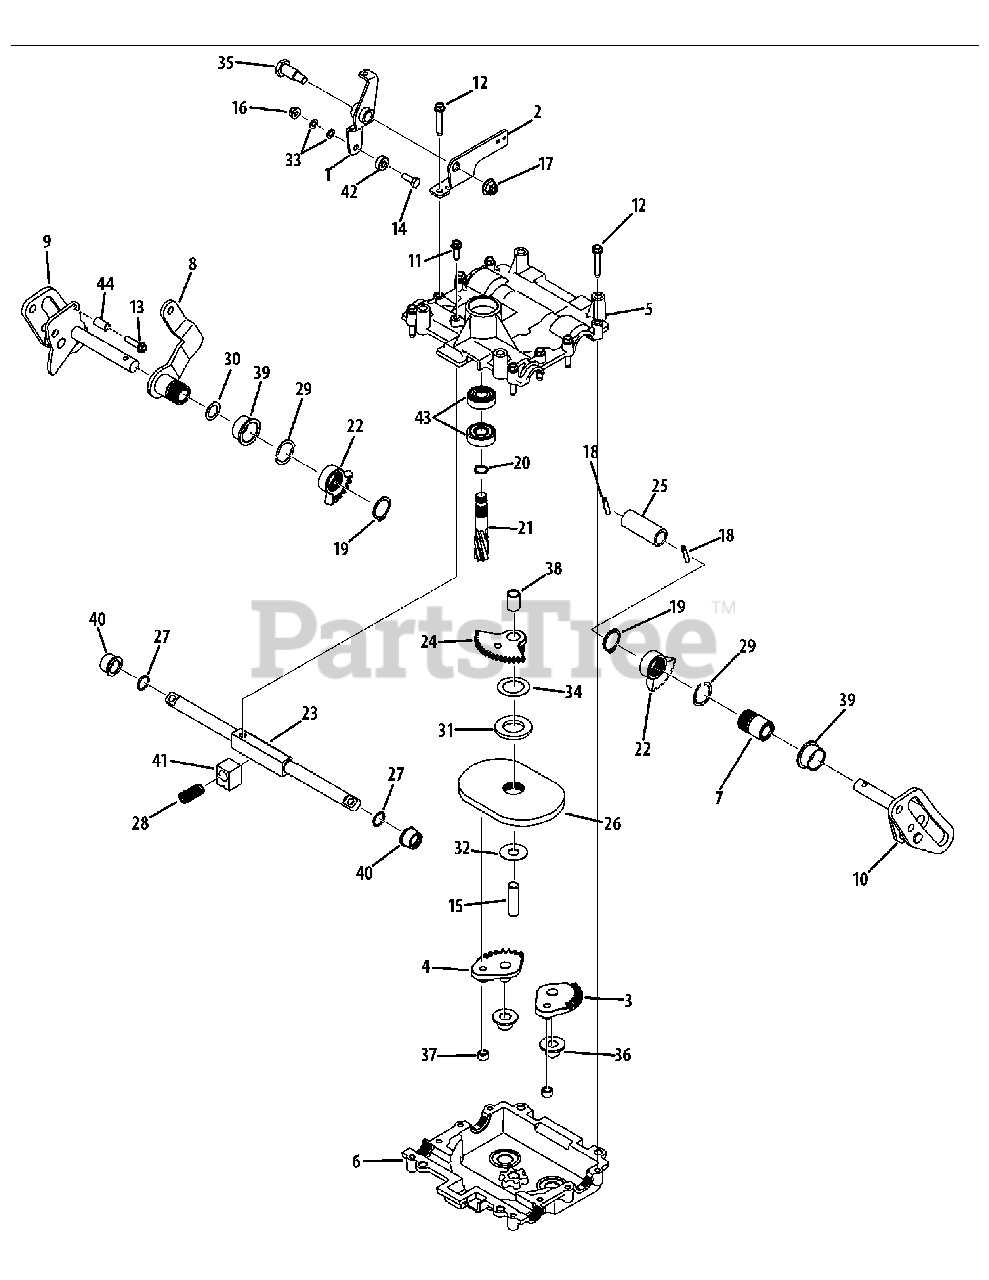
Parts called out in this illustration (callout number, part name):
1	Cam Plate Assembly
2	Neutral Bracket
3	LH Steering Gear Assembly
4	RH Steering Gear Assembly
5	Upper Steering Housing
6	Lower Steering Housing
7	Vertical Hydro LH Arm Assembly
8	Vertical Hydro RH Arm Assembly
9	RH Cam Assembly
10	LH Cam Assembly
11	Hex Washer Screw, 1/4-20 x 0.750
12	Hex Washer Screw, 1/4-20 x 1.500
13	Hex Washer Screw. 1/4-20 x 1.000
14	Hex Screw, 1/4-20 x .75
15	Steering Shaft
16	Hex Lock Nut, 1/4-20
17	Flange Lock Nut, 3/8-16
18	Spirol Pin, 3/16 x 1.00
19	Snap Ring, 1.0
20	Retaining Ring, .56
21	Pinion Gear, 7-Tooth
22	Steering Gear, 26-Tooth
23	Synchro Rack Gear
24	Steering Gear, 53-Tooth
25	Speed Cam Tube
26	Hydro Steering Cam
27	O-Ring, .625 x .07
28	Compression Spring, .531 x 1.25
29	Wave Spring, 24.22 x 32 x 1.98
30	Flat Washer, .635 x .930 x .033
31	Flat Washer, 1.01 x 1.75 x .172
32	Flat Washer, .508 x 1.325 x .040
33	Flat Washer, .260 x .455 x .048
34	Thrust Washer, 1.007 x 1.542 x .03
35	Shoulder Screw, 3/8-16 x .500 x .835
36	Flange Bearing, .5 x .700
37	Sleeve Bearing, .437 x .3425
38	Sleeve Bearing, .623 x .5025 x .800
39	Sleeve Bearing, 1.2 x 1.00
40	Flange Bearing, .625 x .875
41	Rack Caster Bearing
42	Ball Bearing, .25 x .6875 x .25
43	Ball Bearing, .5625 x 1.375 x .4375
44	Spacer, .260 x .375 x .75
